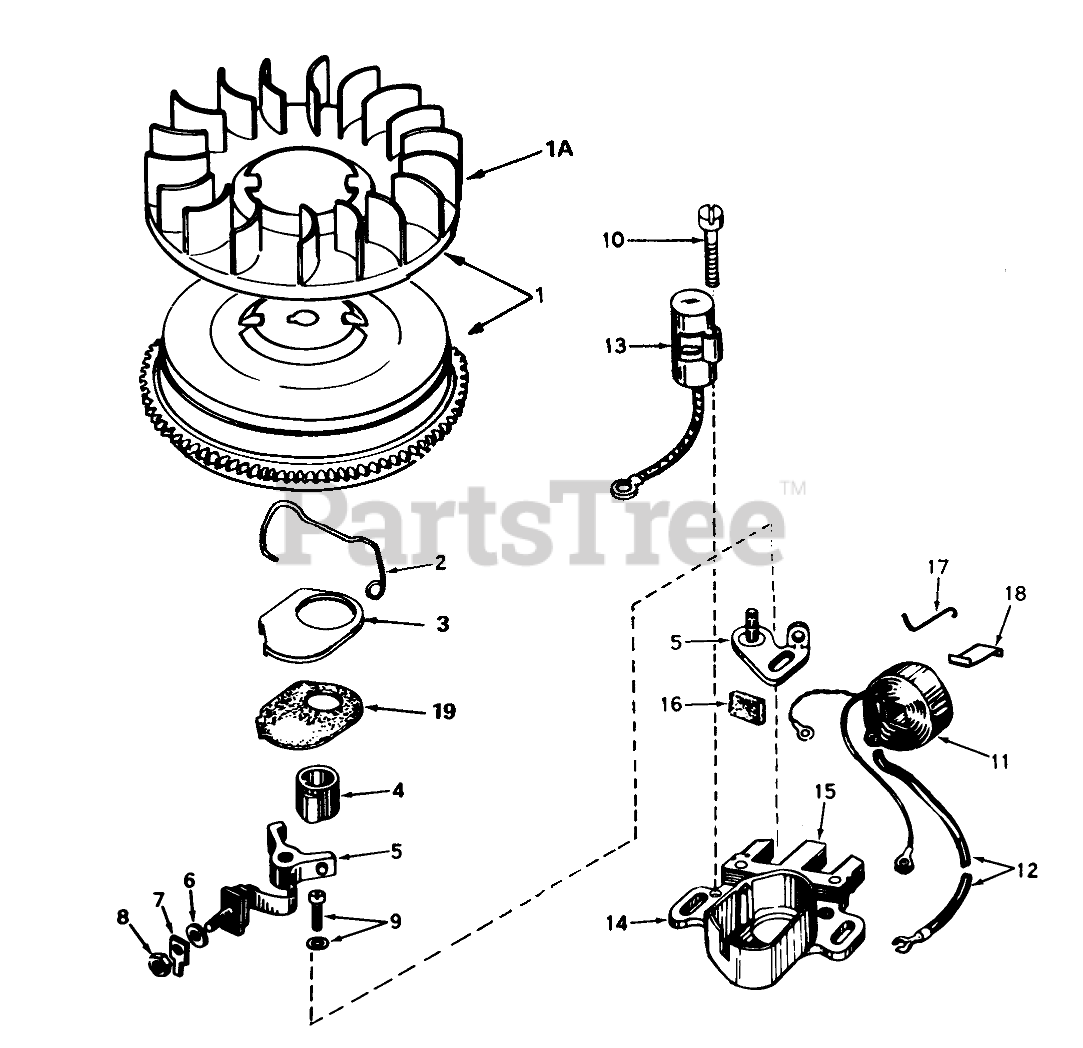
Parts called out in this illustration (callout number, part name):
1	Flywheel (Incl. Ref. #1A)
2	Spring Breaker Box
3	Cover-Dust
4	Cam-Breaker
5	Breaker Assy.
7	Terminal, Ground
9	Breaker Screw
10	Condenser Screw
11	Coil Assy. (Inc. Ref. #12)
12	Wire, Lead
13	Condenser
14	Core & Plate
15	Stator Assy. (Incl. Ref. #2, 3, 5 thru 14 & 16 thru 19)
16	Felt,Cam Wiper
17	Clip, Coil
18	Spring Coil Wedge
19	Gasket-Dust Cover
19	Gasket, Dust Cover
